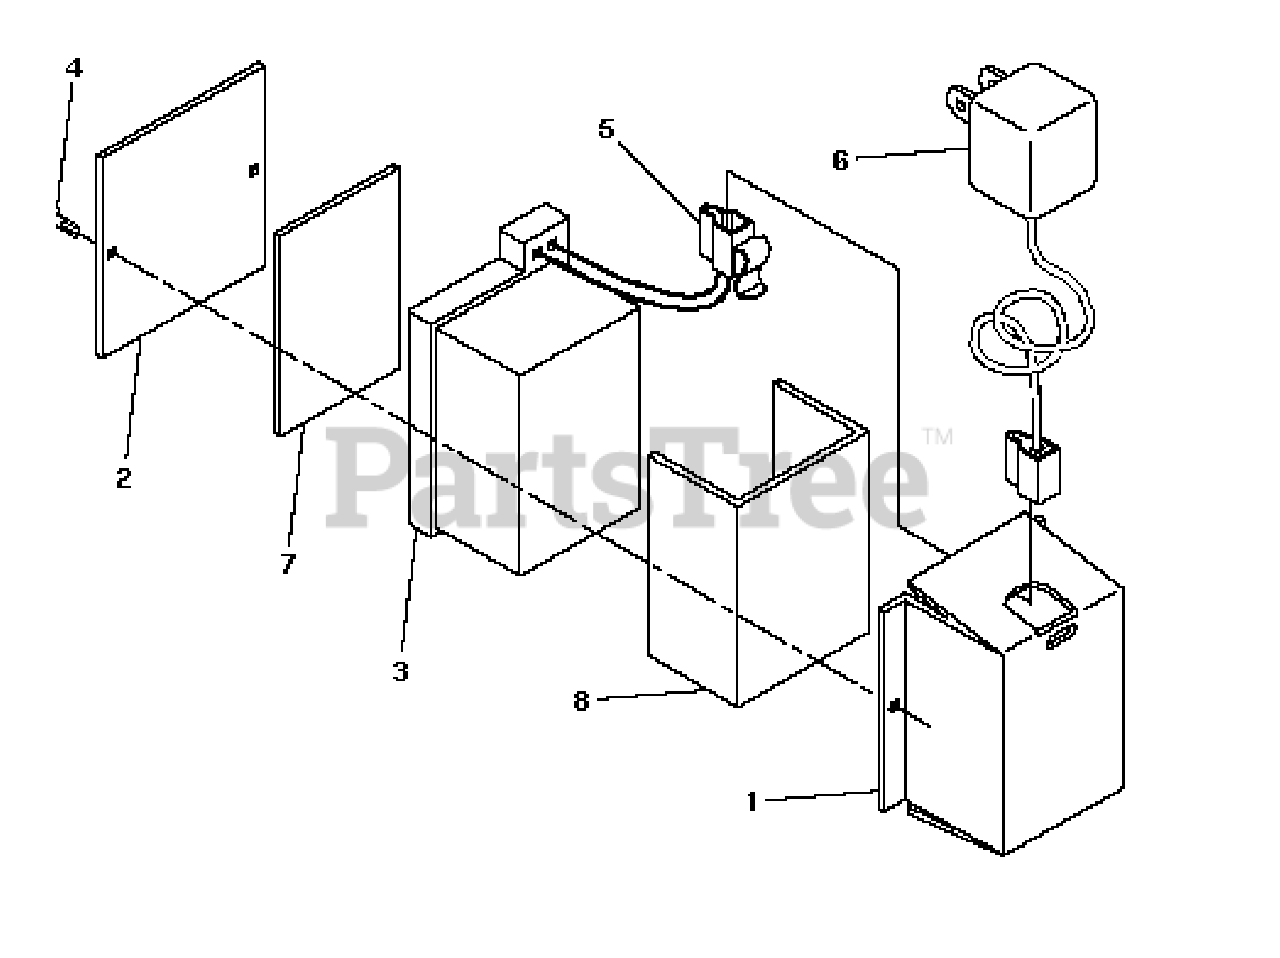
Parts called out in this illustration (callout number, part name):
1	Battery Bracket
2	Battery Cover
3	Battery Kit
4	Hex Washer Head Screw #10-24 x 1/2
5	Connector Mounting Clip
6	Battery Charger
7	Battery Pad
8	Battery Wrap
